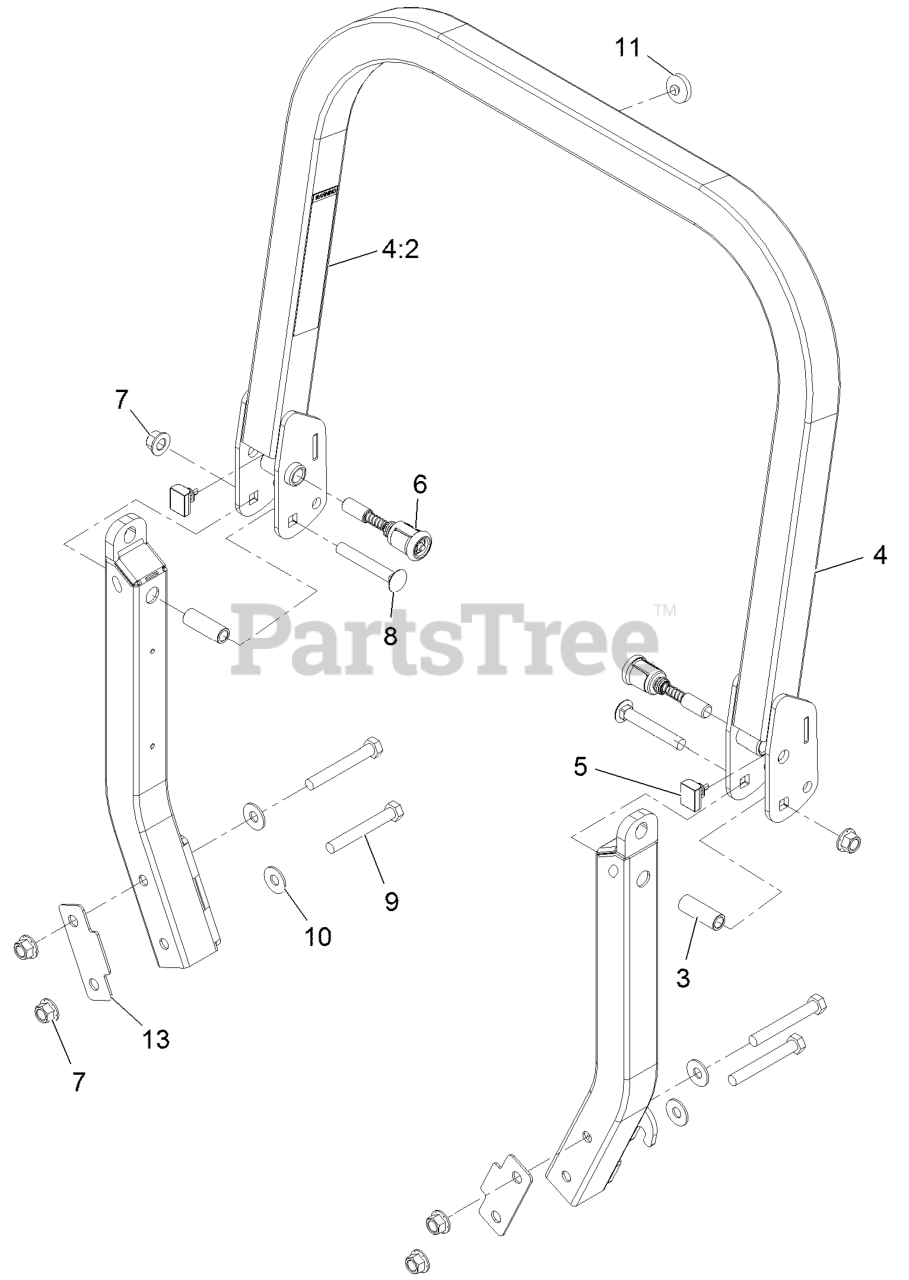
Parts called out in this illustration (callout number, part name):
4	UPPER ROPS ASM
4:2	DECAL-WARNING, FOLDING RO
5	BUMPER-ROPS
6	PIN-SPRING
7	Nut-Lock 1/2-13
8	SCREW-CARR
9	WASHER-LOCK
10	WASHER-SPRING
11	BUMPER-PUSH-IN, RUBBER
